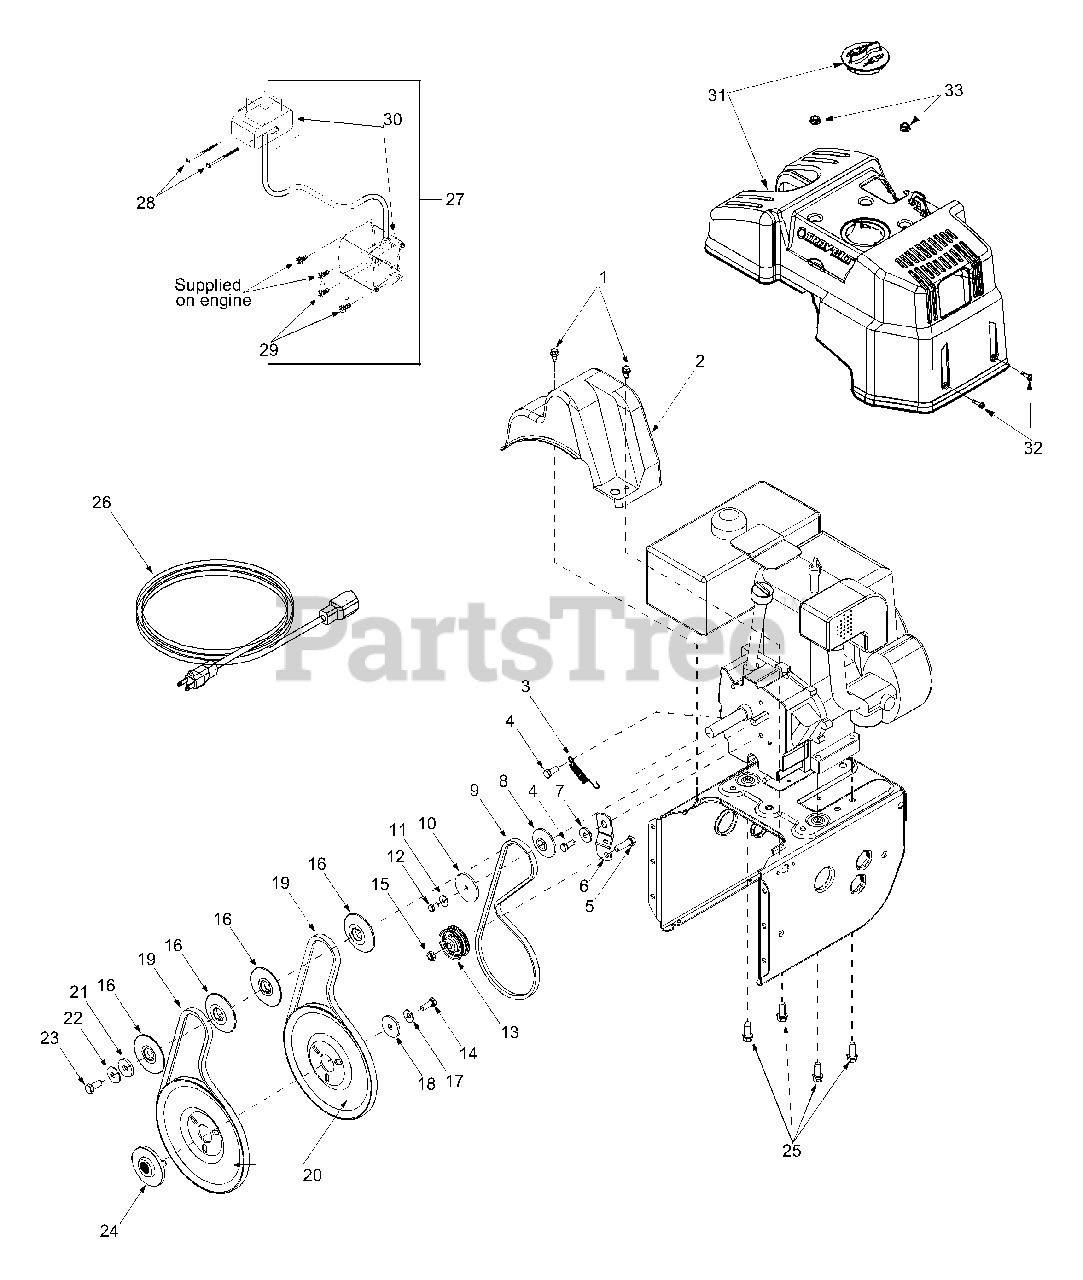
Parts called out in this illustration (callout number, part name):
1	Hex Washer Screw 1/4-20 x.625
2	Belt Cover
3	Extension Spring
4	Hex Screw 5/16-24 x.75
5	Hex Cap Screw 3/8-16 x 1.25
8	Pulley Half
9	V-Belt
10	Pulley Half
11	Bell Washer
12	Hex Cap Screw 1/4-28 x.50
13	Flat Idler
14	Lock Hex Cap Screw 5/16-24
15	Lock Jam Nut 3/8-16
16	Pulley Half
17	Bell Washer
18	Flat Washer
19	Belt
20	Auger Pulley
21	Flat Washer 3/8 x 1.25 OD
22	Bell Washer
23	Hex Cap Screw 3/8-24
24	Adapter Pulley
25	Hex Screw 3/8-16 x 1.0
26	Extension Cord
27	Electric Start Kit
28	Hex Screw #6-32 x 2.5
29	Hex Screw 1/4-20 x.500
30	Electric Starter
31	Engine Shroud Assembly
32	Screw #10-16 x.75
33	Flange Lock Nut 5/16-18
